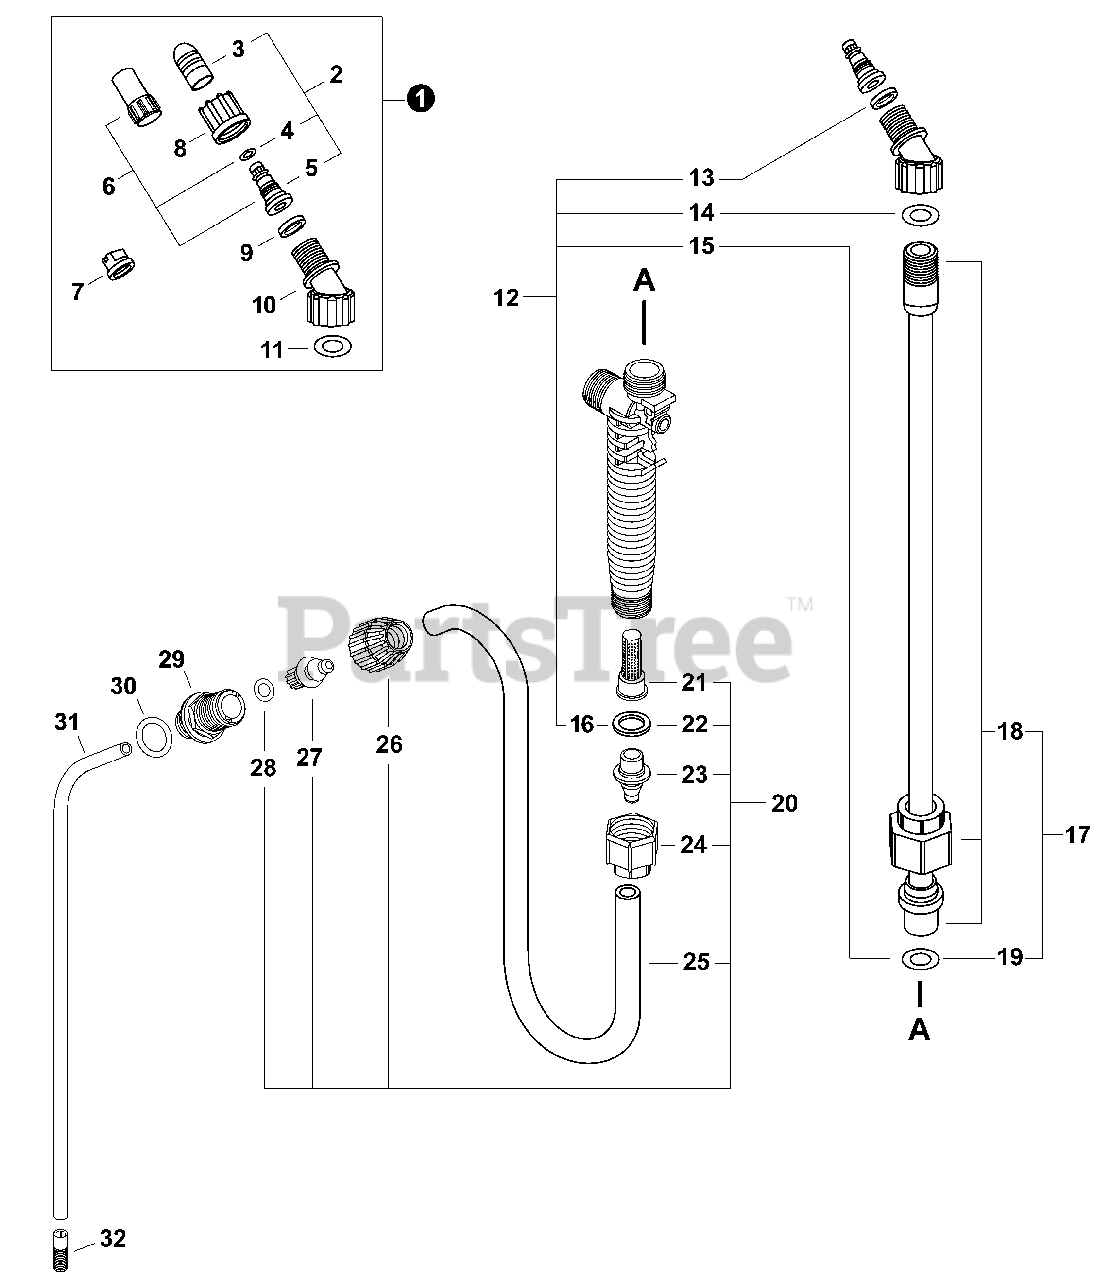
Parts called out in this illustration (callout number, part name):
1	NOZZLE KIT
2	NOZZLE KIT, BRASS
3	CAP, NOZZLE - BRASS
4	O-RING, NOZZLE
5	BODY, NOZZLE
6	NOZZLE KIT, PLASTIC
7	NOZZLE, FLAT FAN
8	NUT, NOZZLE
9	GASKET, NOZZLE
10	ELBOW, NOZZLE
11	O-RING, ELBOW
12	GASKET KIT, WAND
13	GASKET, NOZZLE
14	O-RING, ELBOW
16	GASKET, ADAPTER
17	WAND ASSY, PLASTIC
18	WAND, PLASTIC
20	HOSE KIT
21	FILTER, SPRAY GUN
22	GASKET, ADAPTER
23	ADAPTER, HOSE - BLACK
24	NUT, HOSE
26	NUT, TANK
27	ADAPTER, HOSE - WHITE
28	O-RING, ADAPTER
29	OUTLET, TANK 15/16
30	O-RING, TANK OUTLET
31	TUBE, OUTLET 16-1/4"
32	FILTER, OUTLET
